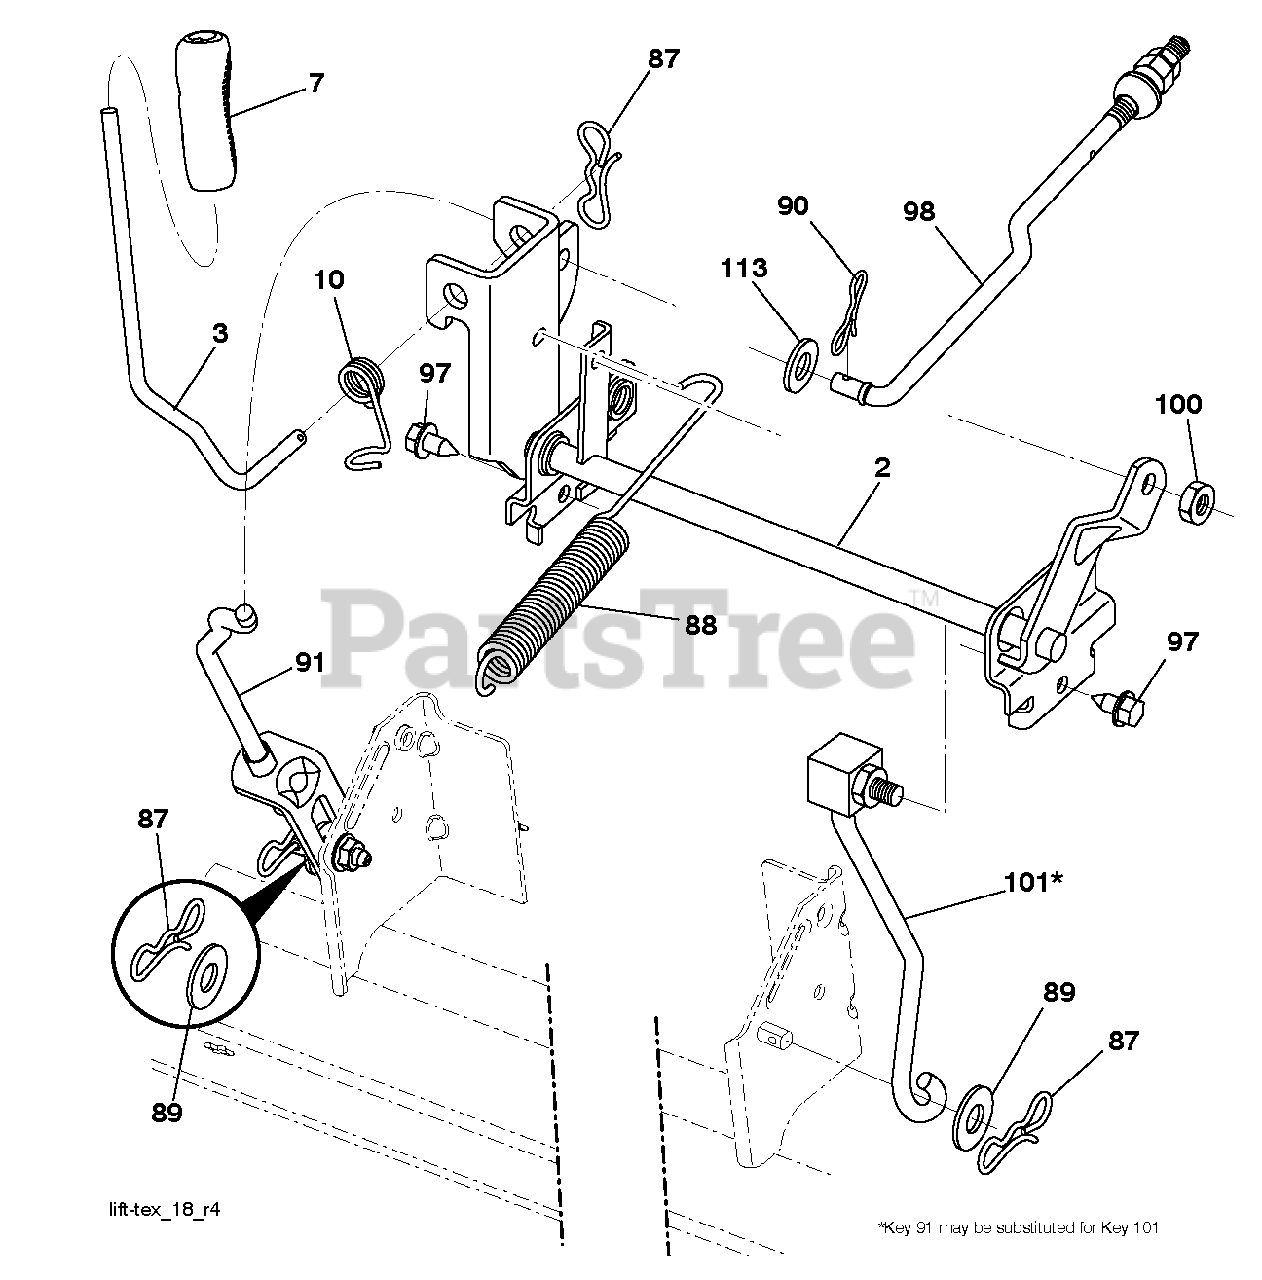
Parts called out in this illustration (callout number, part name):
2	SHAFT.ASM.CROSS.LIFT
3	LEVER.LIFT.HANDLE.LT
7	GRIP.HANDLE.LIFT.PVC.BLACK
10	SPRING.TORSION.LIFT.HANDLE
87	PIN.COTTER.7/16.BOW TI.
88	SPRING.LIFT.ASSIST
89	WASHER.CLEAR.ZINC
90	PIN.COTTER.5/16.BOW TI
91	LINK.ASM.LIFT.REAR
97	SCREW, 3/8-16X3/4
98	LINK.ASM.SUSP.FRONT.MWR.10.5
100	LOCKNUT
101	LINK.ASM.LIFT.FIXE.38/42/46"
